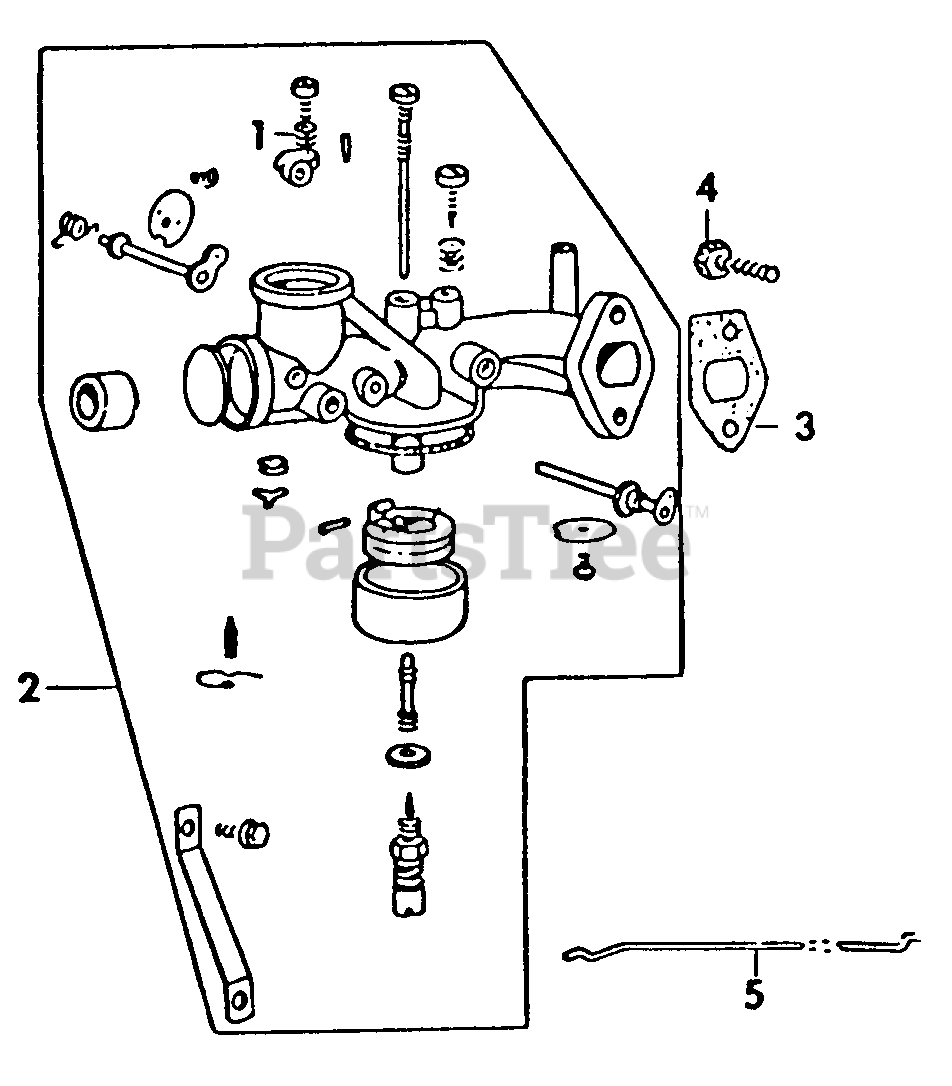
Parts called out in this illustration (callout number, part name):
1	Spring, Throttle Adjusting
2	Carburetor Assy
3	Gasket, Carburetor
4	Screw, Carburetor Mounting
5	Link, Choke
